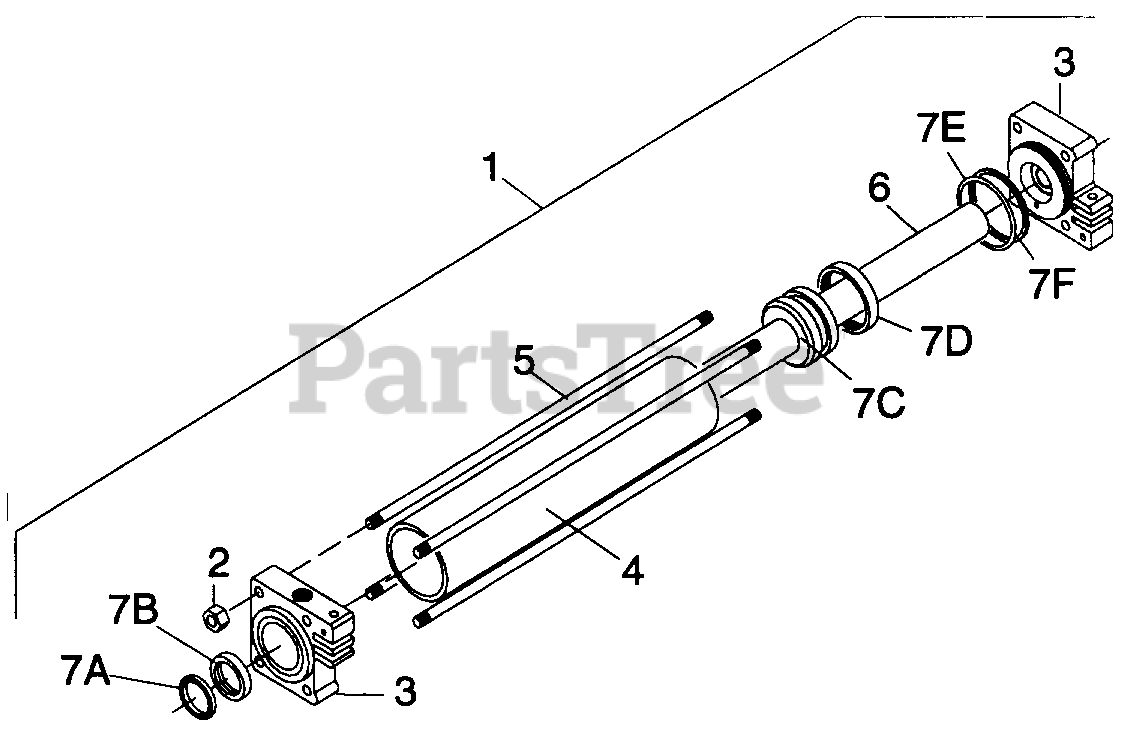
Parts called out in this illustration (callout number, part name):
1	2-1/2 x 10-5/8 Double acting hydraulic cylinder
2	7/16 NC Hex nut
3	2-1/2 OD x 1-1/4 ID Guide
4	2-1/2 ID x 3/16 Wall x 12-3/4 Cylinder tube
5	.385 Dia. x 16 Tie rod
6	1-1/4 x 2-1/2 Piston rod assembly
7A	1-1/4 ID x 1-1/2 OD Rod wiper
7B	1-1/4 x 1-5/8 x 5/16 U-Cup seal
7C	3/4 x 7/8 O-Ring
7D	2-1/2 Piston seal
7E	2-1/4 x 2-1/2 O-Ring
7F	2-1/4 x 2-1/2 Back-up ring
